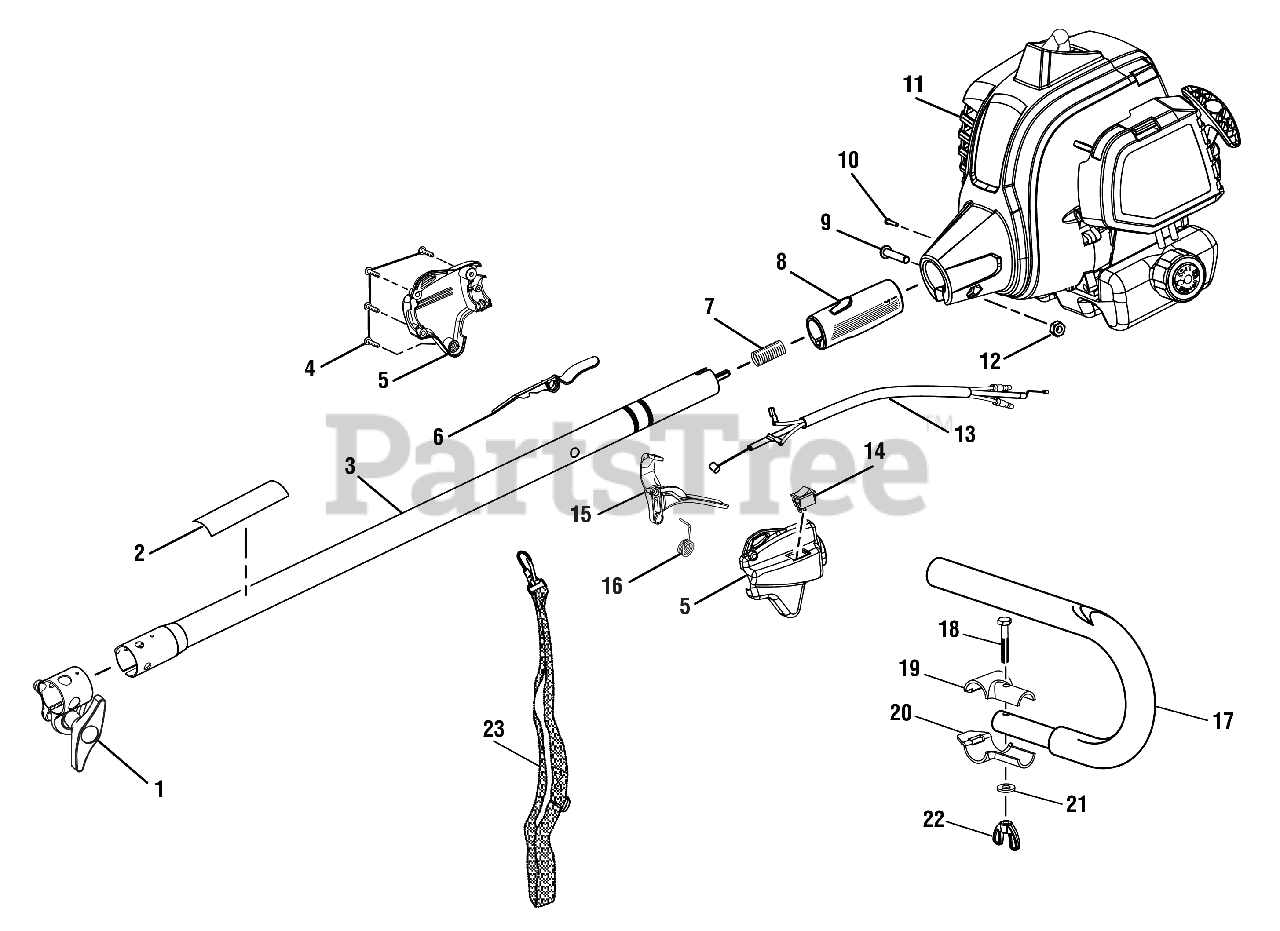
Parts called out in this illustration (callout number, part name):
1	Boom Clamp Assembly
2	Warning Icon Label
3	Upper Boom Assembly
4	Screw (M4 x 20 mm, T20 Torx Pan Hd. S.T.)
5	Control Handle Assembly (Inc. Key No. 6)
6	Trigger Lock
7	COMPRESSION SPRING
8	Rear Handle Grip
9	Screw (M6 x 30 mm, T27 Torx Button Hd.)
10	Screw (M4 x 8 mm, T25 Torx Pan Hd. T.F.)
11	Powerhead Assembly w/Labels
12	Hex Nut (M6.3 x 1)
13	Throttle Cable and Wire Assembly
14	Stop Switch (Momentary Contact)
16	Torsion Spring (Throttle Trigger)
17	"J" Handle and Grip
18	Bolt (1/4-20 x 1-1/2 in., Hex Hd.)
19	Top "J" Handle Clamp
20	Bottom "J" Handle Clamp
21	Washer (ID7.25 x OD16 x 1.5t)
22	Wing Nut (1/4-20, Plastic)
23	Shoulder Harness Assembly
